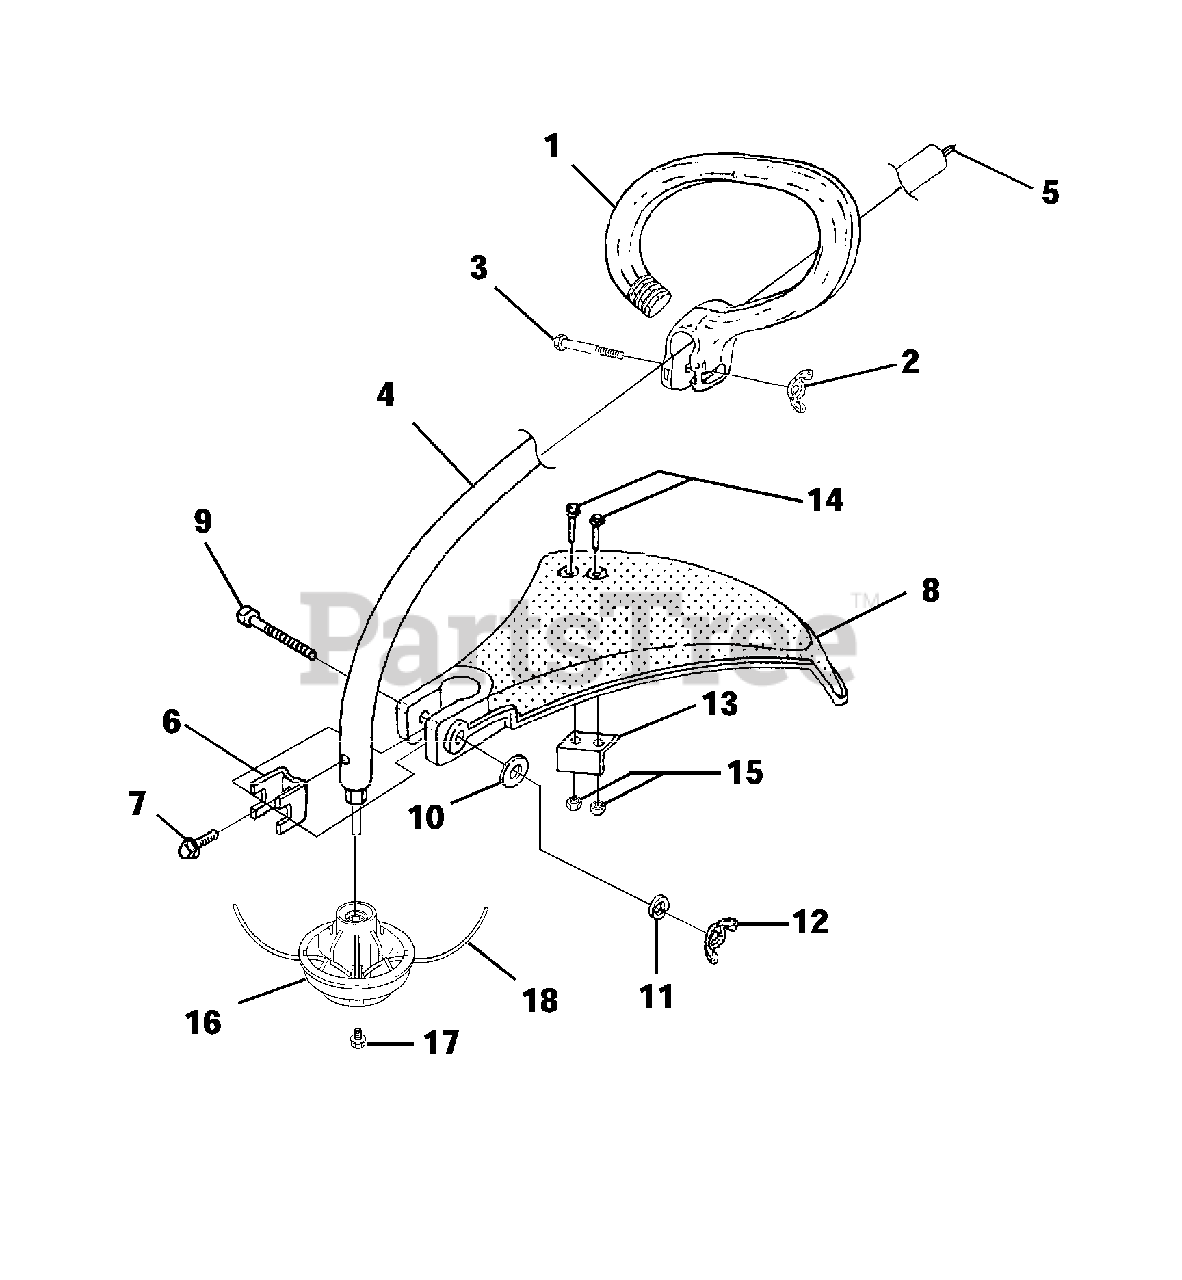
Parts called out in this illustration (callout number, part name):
1	HANDLE ASSY.-Front
2	NUT-Wing, Washer Faced (1/4-20)
3	SCREW-Cap Hex Hd.
4	DRIVESHAFT HOUSING ASSY.
5	SHAFT-Flexible
6	CLAMP
7	SCREW-Sems Hex Hd. (#10-24 X 3/8")
8	DEFLECTOR & BLADE KIT (55 Deg.)
9	SCREW-Cap Hex Hd. (10-24 X 2")
10	WASHER-Flat (1/4")
11	WASHER-Lock (1/4")
12	NUT-Wing, Washer Faced (1/4-20)
13	BLADE-Cut-Off
14	SCREW-Mech. Hex Hd. (10-24 X 7/8")
15	NUT-Hex (10-24)
16	STRINGHEAD-Pro-Cut w/line
17	SCREW (5/16-18 x 5/8")
18	LINE-Replacement
